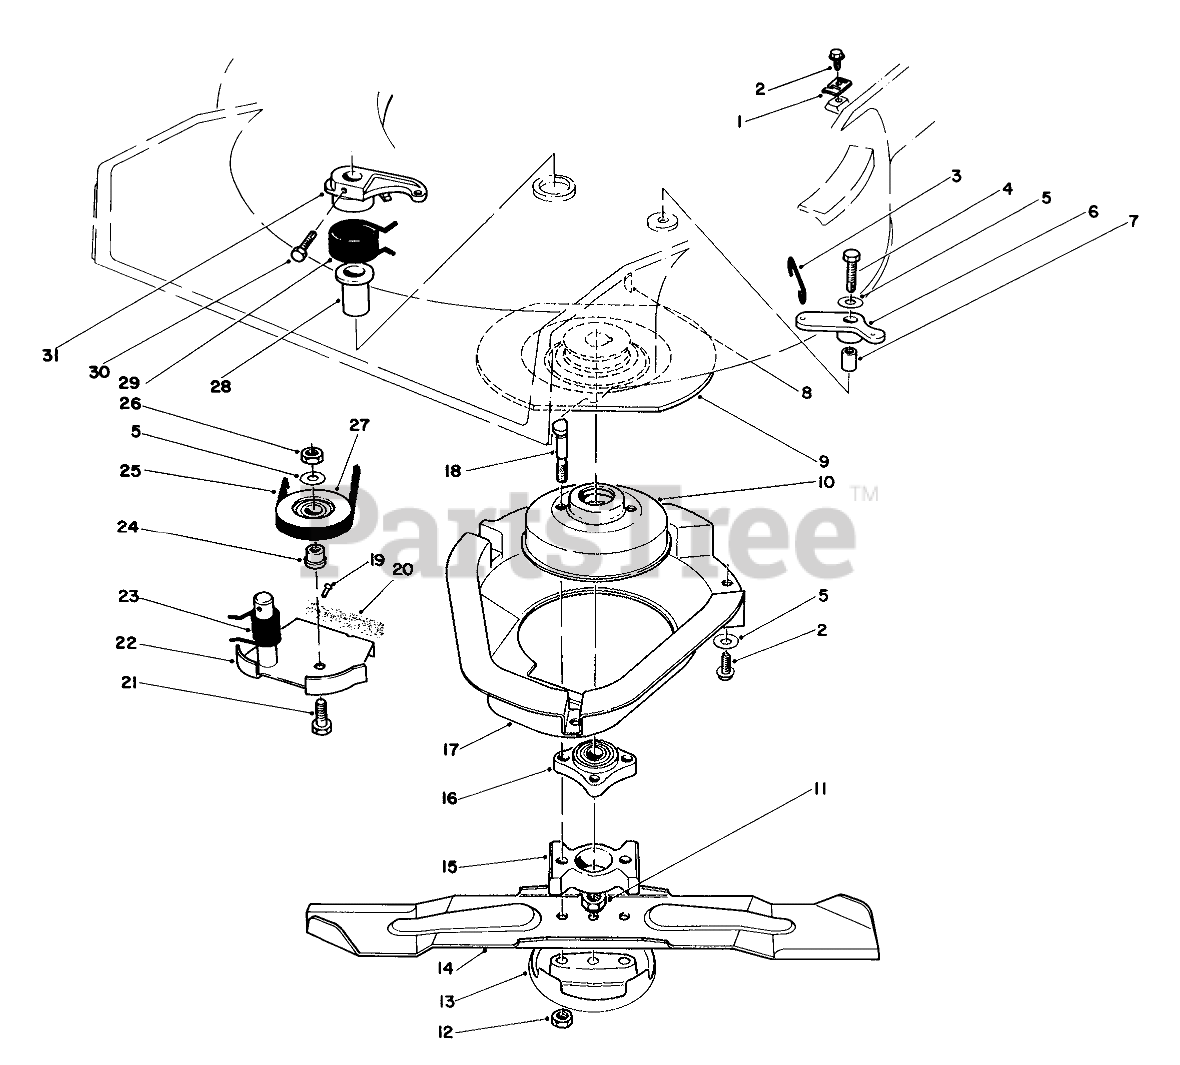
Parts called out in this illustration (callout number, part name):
1	Cable Clamp
2	SCREW-HWHTF
3	Link Control
4	SCREW-HH
5	WASHER-FLAT
6	Bell Crank
7	Sleeve-Bell Crank
8	KEY-WOODRUFF
9	Flywheel
10	Brake Drum
11	NUT-LOCK, NI
12	Nut
13	Anti Scalp Cup
14	BLADE-21in
15	Spacer Blade
16	HUB ASM
17	SHIELD BBC
18	BOLT-BLADE
19	.185 DIA X .375 RT +
20	Paid
21	SCREW-HH
22	Brake Plate
23	SPRING-TORSION
24	HUB-PULLEY, IDLER
25	V-Belt
26	NUT-LOCK, NI
27	PULLEY-IDLER
28	BUSHING PM
29	TORSION SPRING
30	SCREW-HH
31	Lever
